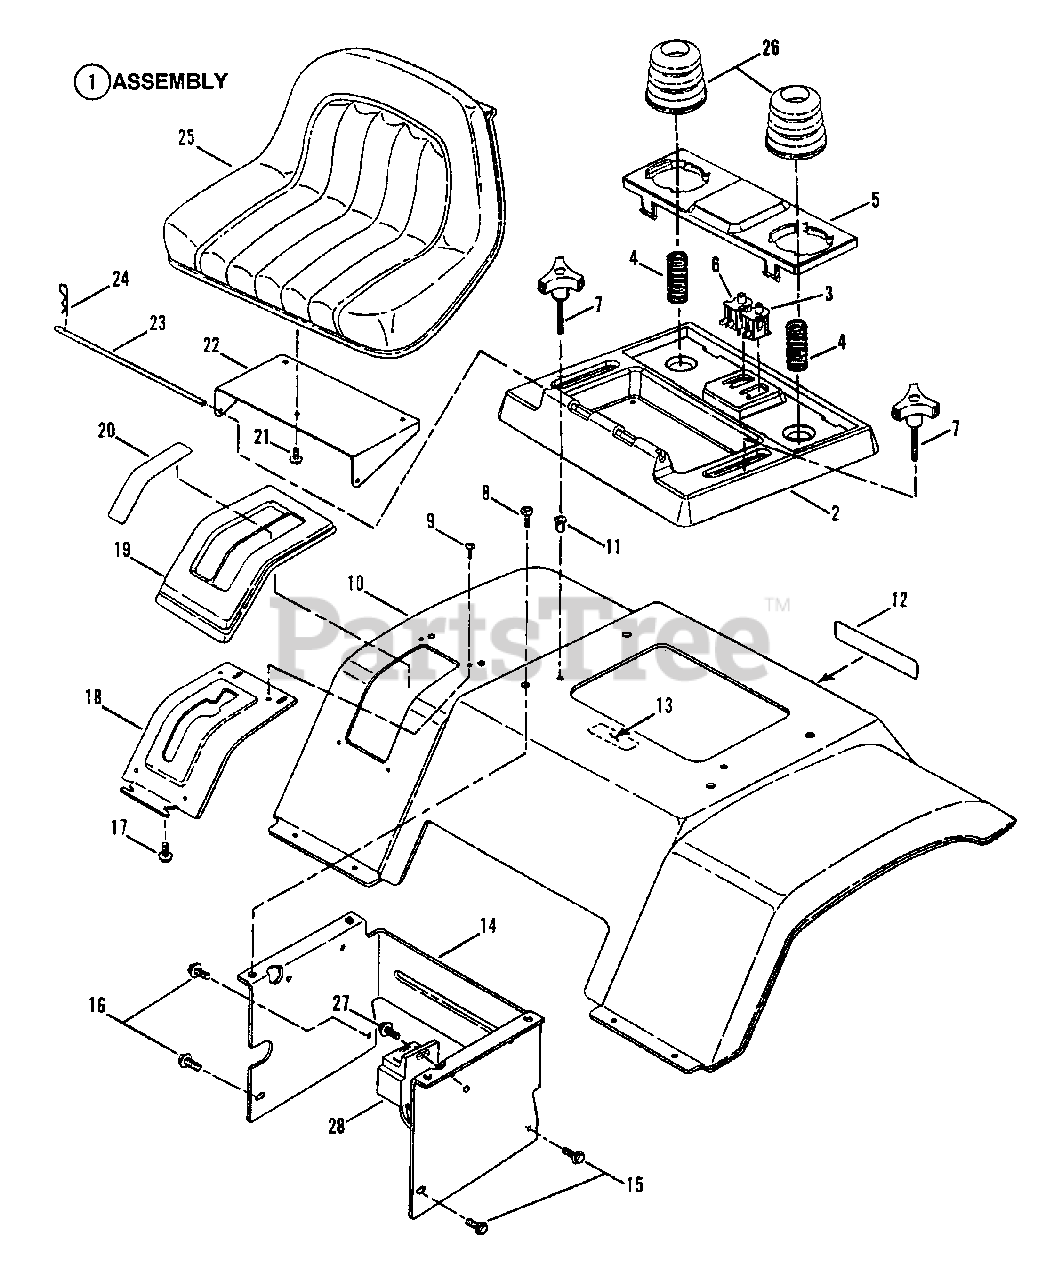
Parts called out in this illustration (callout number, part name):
1	ASSEMBLY, Seat Support
2	SUPPORT, Seat
3	SWITCH, Seat, Gray, (N.C.)
4	SPRING, Cushion Holder
5	HOLDER, Cushion
6	SWITCH, Seat
7	KNOB, Seat Adjustment, 5/16-18 x 2"
8	SCREW, 5/16-18 X 5/8" Truss Head Torx
9	SCREW, 1/4-20 x 5/8" Hex Washer Head, Self-Tapping
10	PAN, Seat (Fender)
11	RIV-NUT, 5/16-18 Round
12	DECAL - SNAPPER, 7.28" Molded Logo, Silver Letters & Blue Stripe
13	DECAL - CAUTION, Battery Location
14	SUPPORT, Fender
15	SCREW, 5/16/18 x 5/8" Hex Washer Head, Swage Form
16	SCREW, 5/16/18 x 1 1/4" Hex Washer Head, Swage Form
17	SCREW, #10-16 x 1/2" Hex Washer Head, Self-Tapping
18	DETENT, Shift
19	COVER, Shift
20	DECAL, Shift Cover, 5-Speed
21	BOLT, 5/16-18 x 1/2" Hex Flange Lock, Grade 5
22	BRACKET, Seat Support
23	ROD, Seat Hinge
24	PIN, 3/32 x 1-1/2" Hair
25	SEAT, Operator, V560
26	CUSHION, Seat
27	SCREW, #10-24 x 1/2" Hex Washer Self-Tap (Torx)
28	RECEPTACLE, Female Wire Harness Relay
